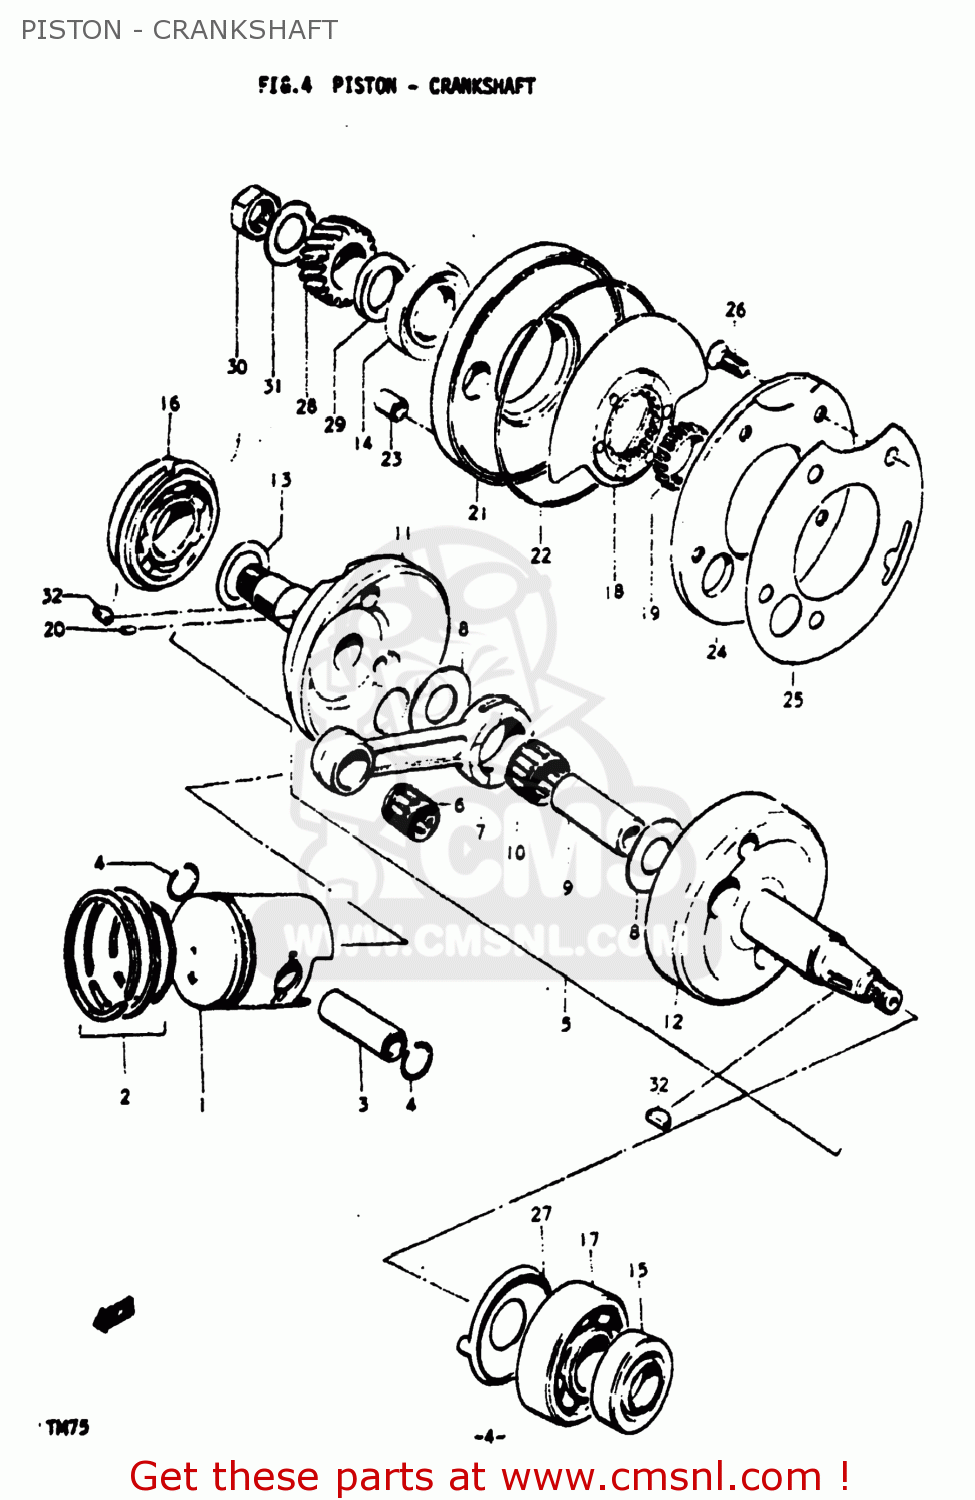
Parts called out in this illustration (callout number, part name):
1	PISTON
2	RING SET,PISTON
3	PIN,PISTON
4	RING,SNAP
5	CRANKSHAFT ASSY
6	BEARING
7	CONNECTING ROD
8	WASHER
9	PIN,CRANK
10	BEARING
11	CRANKSHAFT
12	CRANKSHAFT,LEFT
13	THRUST WASHER
14	OIL SEAL (25X44X7)
15	OIL SEAL
16	BEARING(20X52X15)
17	BEARING(20X47X14)
18	VALVE,ROTARY
19	GUIDE,ROTERY VALVE
20	PIN 3X5
21	SEAT,CRANKCASE OUTER VALVE
22	O RING(D:2.4,ID:100.6)
23	PIN
24	SEAT,INNER VALVE
25	GASKET,ROTERY VALVE INNER SEAT (NAS)
26	SCREW
27	PLATE,CSHAFT OIL GUIDE
28	GEAR,PRIMARY DRIVE
29	SPACER(20X25X10)
30	NUT
31	WASHER
32	KEY
